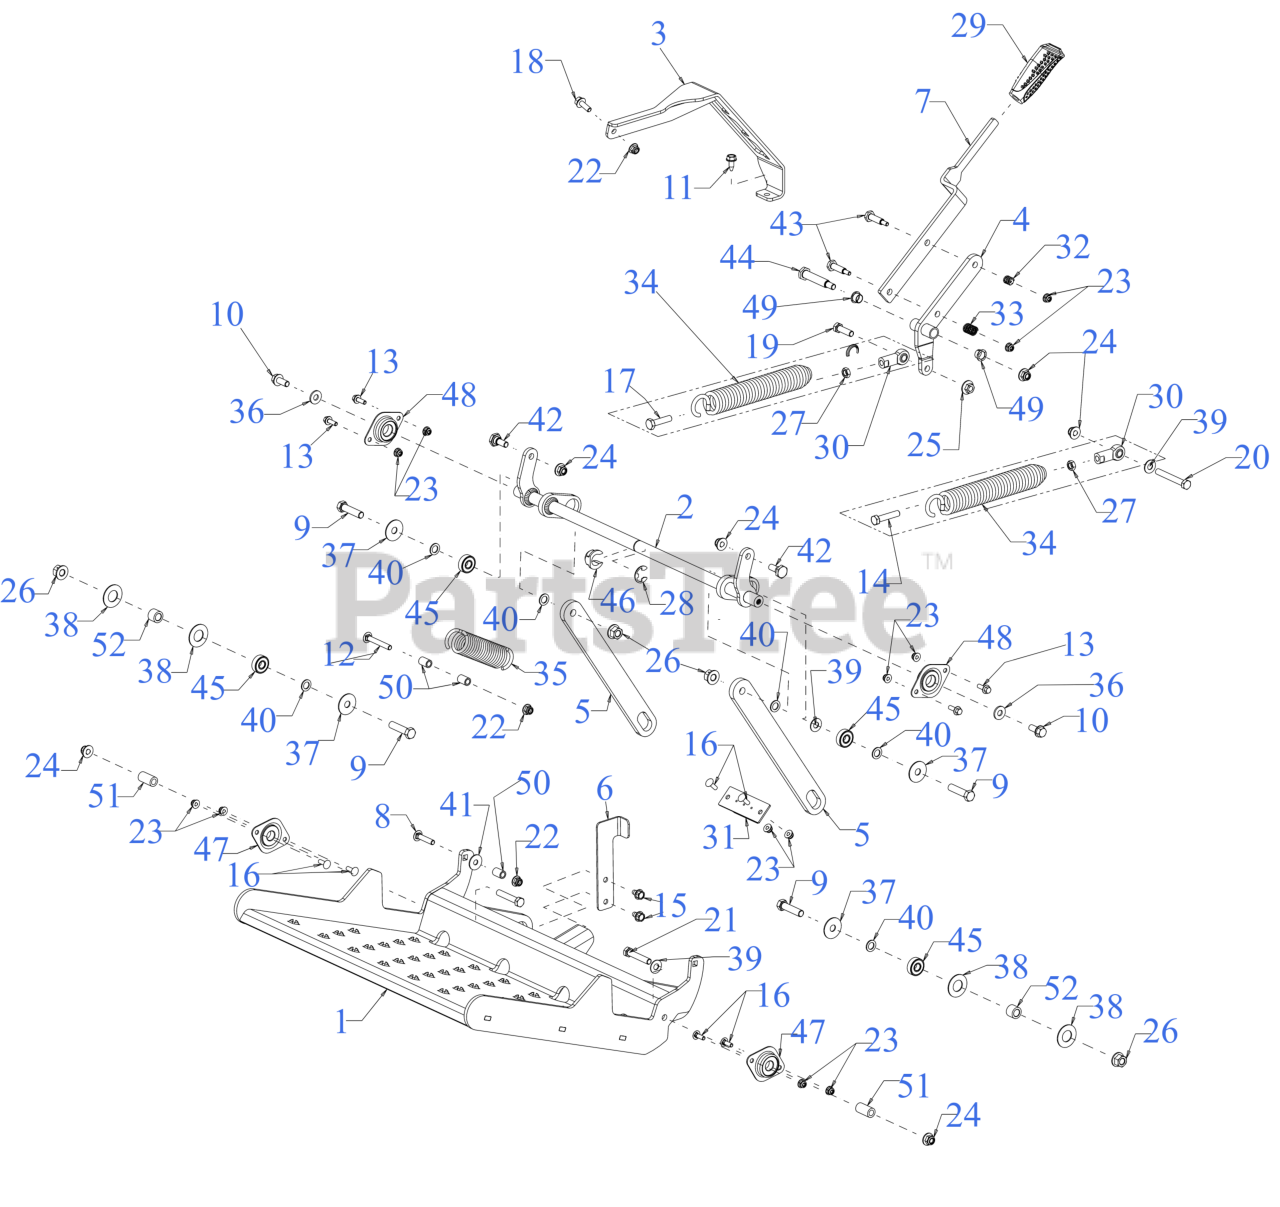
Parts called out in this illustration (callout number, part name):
1	PLATFORM ASSEMBLY
2	ROLLER LINK
3	ADJUSTMENT INDEX
4	ADJUSTMENT ARM
5	SUSPENSION LINK
6	SWITCH BRACKET
7	ADJUSTMENT SPRING LEVER
8	CARRIAGE BOLT 5/16-18 x 1.50
9	SCREW 7/16-20 x 1.75 GR 5
10	SCREW 3/8-16 x .875 GR5
11	SCREW 5/16-18 x .750
12	BOLT 5/16-18 x 2.50 GR1
13	SCREW 1/4-20 x .75 GR5
14	SCREW 3/8-24 x 1.75 GR5
15	SCREW 5/16-18 x .500
16	SCREW 1/4-20 x .75 GR5
17	SCREW 3/8-24 x 1.50 GR8
18	SCREW 5/16-18 x .875 GR5 HXFLG HD
19	SCREW 3/8-16 x 1.25 GR5
20	SCREW 3/8-16 x 2.75 GR5
21	SCREW 3/8-16 x 2.0 GR 8
22	FLANGE LOCK NUT 5/16-18
23	FLANGE LOCK NUT
25	FLANGE LOCK NUT
26	FLANGE LOCK NUT
27	HEX JAM NUT 3/8X24
30	ROD END 3/8 ID
31	SUSPENSION BUMPER
32	COMPRESSION SPRING
33	COMPRESSION SPRING
34	ADJUSTMENT SPRING
35	EXTENSION SPRING 1.478 x 5.729
36	FLAT WASHER .385X.870X.090
37	FLAT WASHER
38	FLAT WASHER
39	FLAT WASHER .401X.88
40	FLAT WASHER .469X.750X.054
41	FLAT WASHER 344X1.00
42	SHOULDER SCREW
43	SHOULDER SCREW
44	SHOULDER SCREW .50 x 2.23 3/8-16
45	BALL BEARING
46	HEX FLANGE SPLIT BEARING
47	BALL BEARING
48	BALL BEARING
49	NYLINER BEARING
50	SLEEVE .33X.50X.75 LG
51	SPACER .380x.624x1.040
52	SPACER .465x.760x.550
